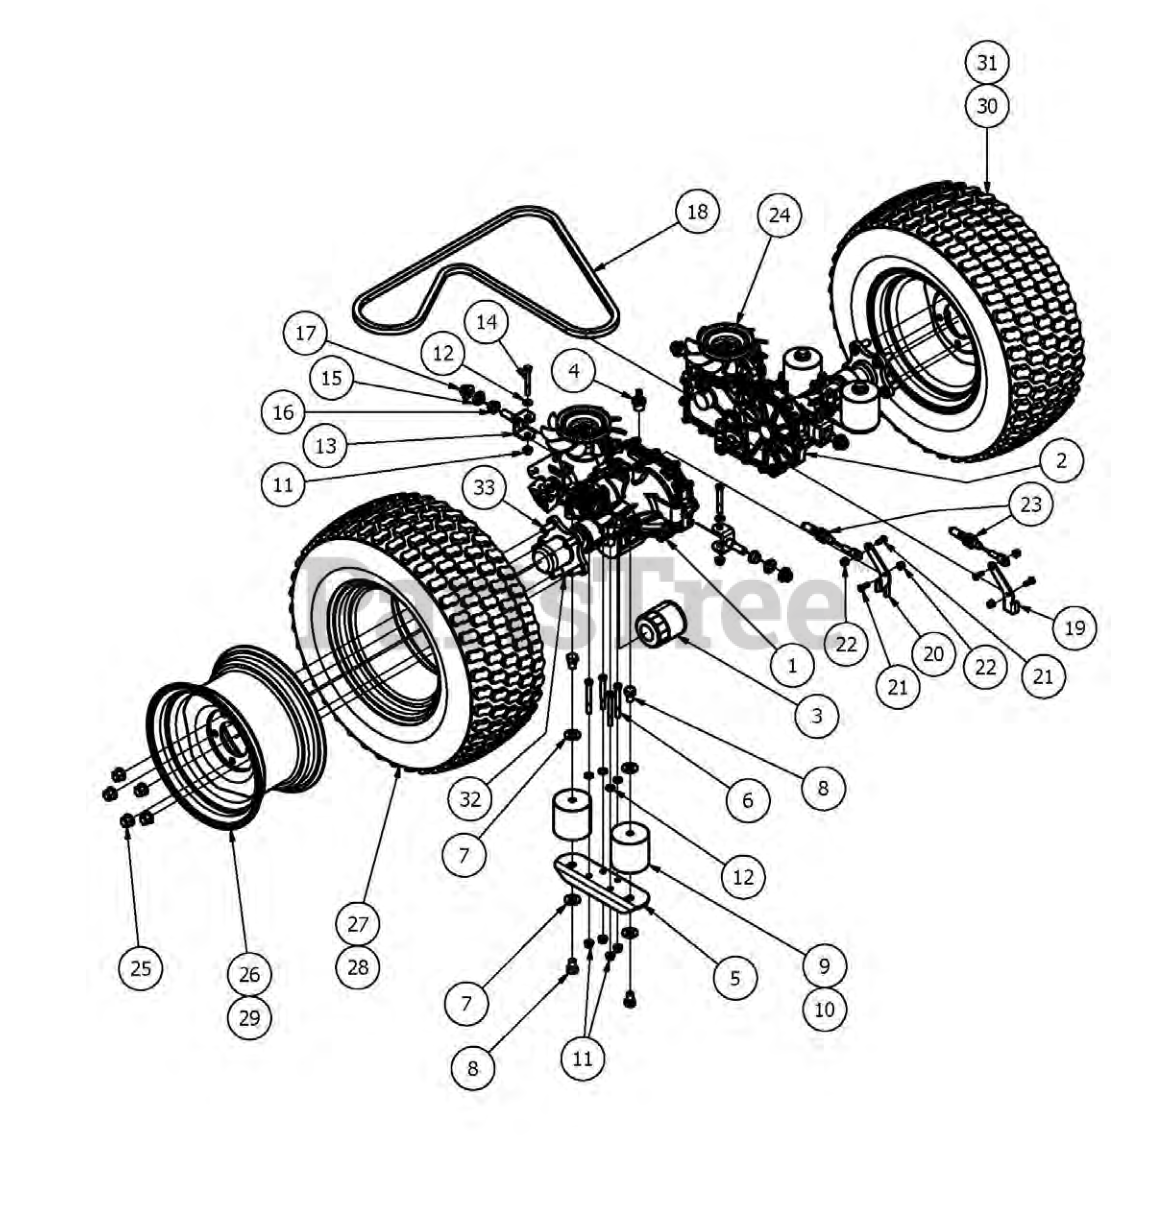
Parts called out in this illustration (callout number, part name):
1	3200 Left transaxle
2	3200 right transaxle
3	ZT Hydraulic Filter
4	45 degree fitting
5	Rear Susp Transaxle Mount
6	5/16" x 3" Hex Bolt
7	1/2" Washer (Grade 8)
8	1/2" x 3/4" Hex Bolt
9	Vibration Mount-Green Dot
10	Vibration Mount-Red Dot (48" Maverick Only)
11	5/16" Flange Nut
12	5/16" Flat Washer
13	Maverick Rear Transaxle Pivot Bracket
14	5/16" x 2 1/2" Bolt
15	515 ID Nylon Shoulder Washer
16	Bronze Bushing - SF-2024-8
17	1/2-13 Nylon Flange Nut
18	75.8" Pump Belt
19	Brake Arm Ext (Right)
20	Brake Arm Ext (Left)
21	1/4" x 3/4" Hex Bolt
22	1/4-20 Nylon Insert flange Nut
23	Brake Cable
24	Fan/Pully Kit for ZT and Maverick
25	Acorn Lug Nut
26	12" Black Wheel
27	23 x 10.50 -12 Tire
28	23 x 8.50-12 Tire (48" Maverick Only)
29	12 x 7" Black Wheel (48" Maverick Only)
30	Tire and Wheel Assembly (26 and 27)
31	Tire and Wheel Assembly (28 and 29) (48" Maverick Only)
32	Transaxle Hub
33	Transaxle Wheel Stud
